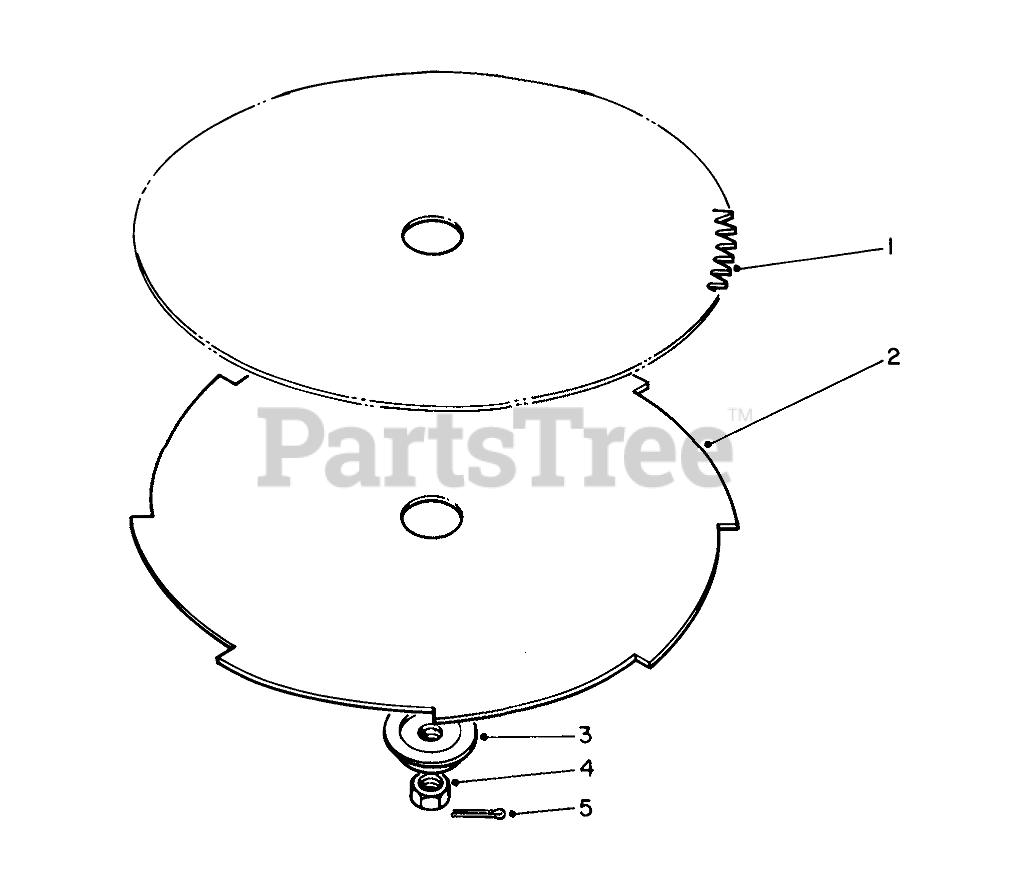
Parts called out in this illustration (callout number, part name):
1	SAW BLD PKG(8", 80T)
2	BRUSH BLD PKG(8",8T)
3	Adapter-Blade
5	1/16 X 1 LG COTTER PIN
